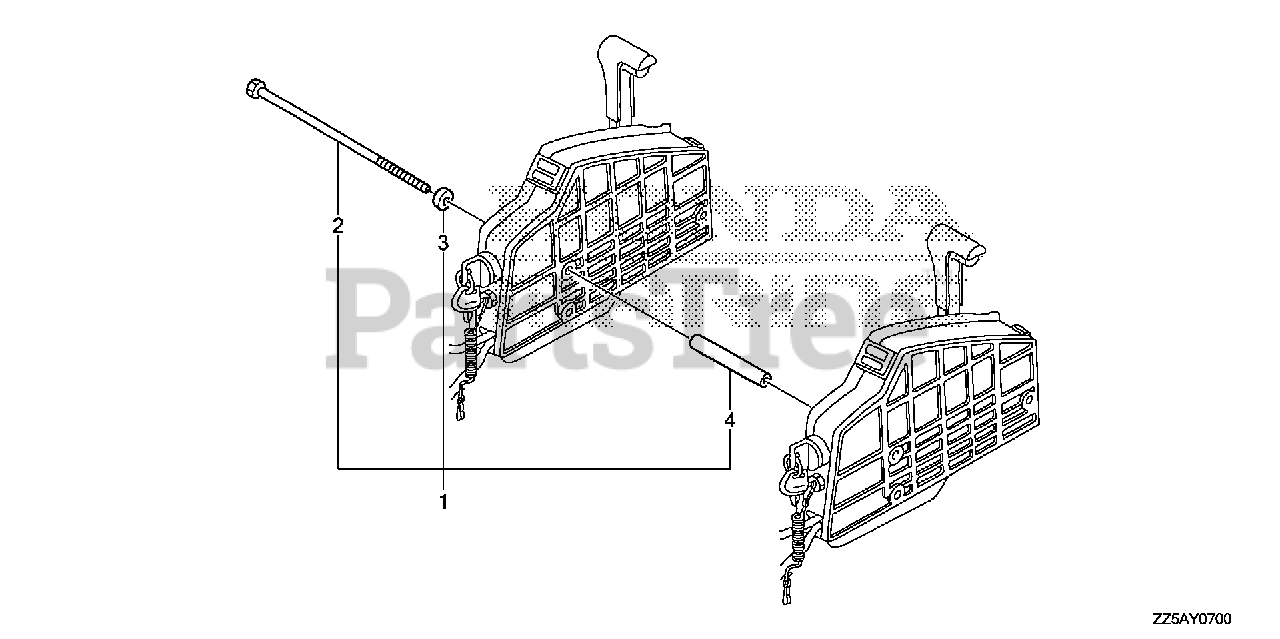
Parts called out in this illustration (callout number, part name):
1	BOLT KIT, SIDE REMOTE CONTROL
2	BOLT, SPECIAL (6X220)
3	COLLAR, DISTANCE (A)
4	COLLAR, DISTANCE (B)
